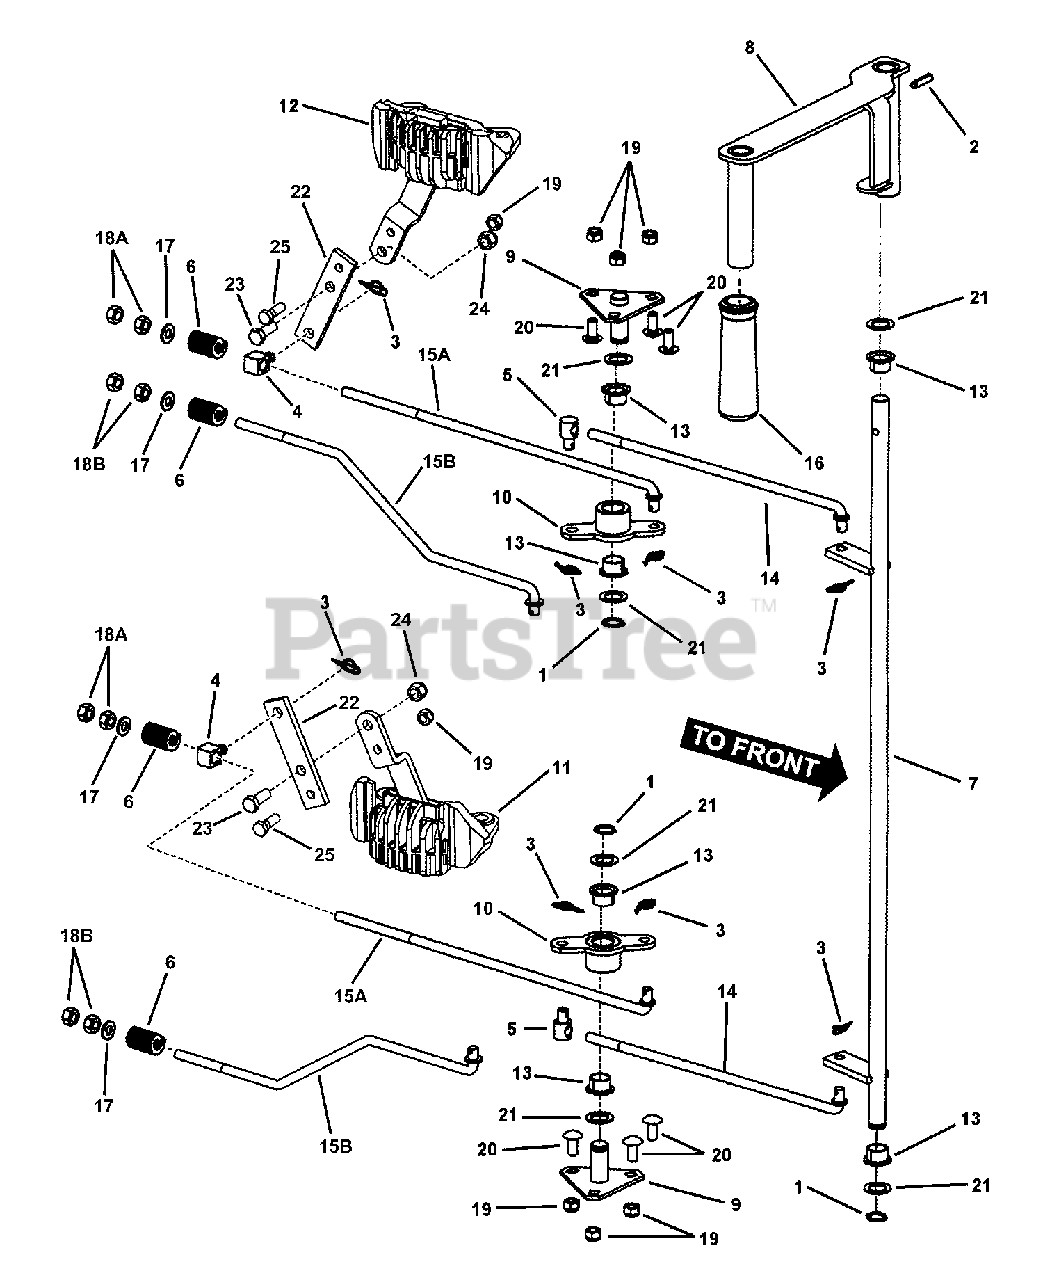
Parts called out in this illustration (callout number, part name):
1	RING, 5/8" External Retaining
2	GROOVE PIN, 1/4 x 1-1/4" long
3	PIN, 3/8" Self Locking Cotter
4	SWIVEL, 3/8" Thru Hole, Special
5	SWIVEL, 3/8-24 Adjustment
6	SPRING, Rectangular Wire Die, Blue
7	WELDMENT, Brake Rod Crossrod
8	WELDMENT, Park Brake Handle
9	WELDMENT, Brake Linkage Pivot
10	WELDMENT, Brake Linkage Bellcrank
11	PACKAGE, Left Hand Disc Brake
12	PACKAGE, Right Hand Disc Brake
13	BUSHING, Teflon Impregnated
14	FRONT LINKAGE, Park Brake (3/8-24 thread)
15A	REAR LINKAGE, Park Brake (3/8-24 thread)
15B	ROD, Brake Rear (3/8-16 thread)
16	GRIP, Parking Brake
17	WASHER, 3/8" SAE Flat
18A	NUT, 3/8-24, Hex Jam, GR 5 or B
18B	NUT, 3/8-16, Hex Jam, GR 5 or B
19	NUT, 5/16-18 HEX NYLON LOCK
20	BOLT, 5/16-18 x 3/4" Short Neck Carriage, GR 5
21	WASHER, .64 I.D. x .99 O.D. x .05 Flat
22	EXTENSION, Brake Lever
23	BOLT, 3/8-16 X 1" GD5 CZ
24	NUT, 3/8-16 HEX NYLON LOCK
25	BOLT, 5/16-18 X 3/4 GD5
